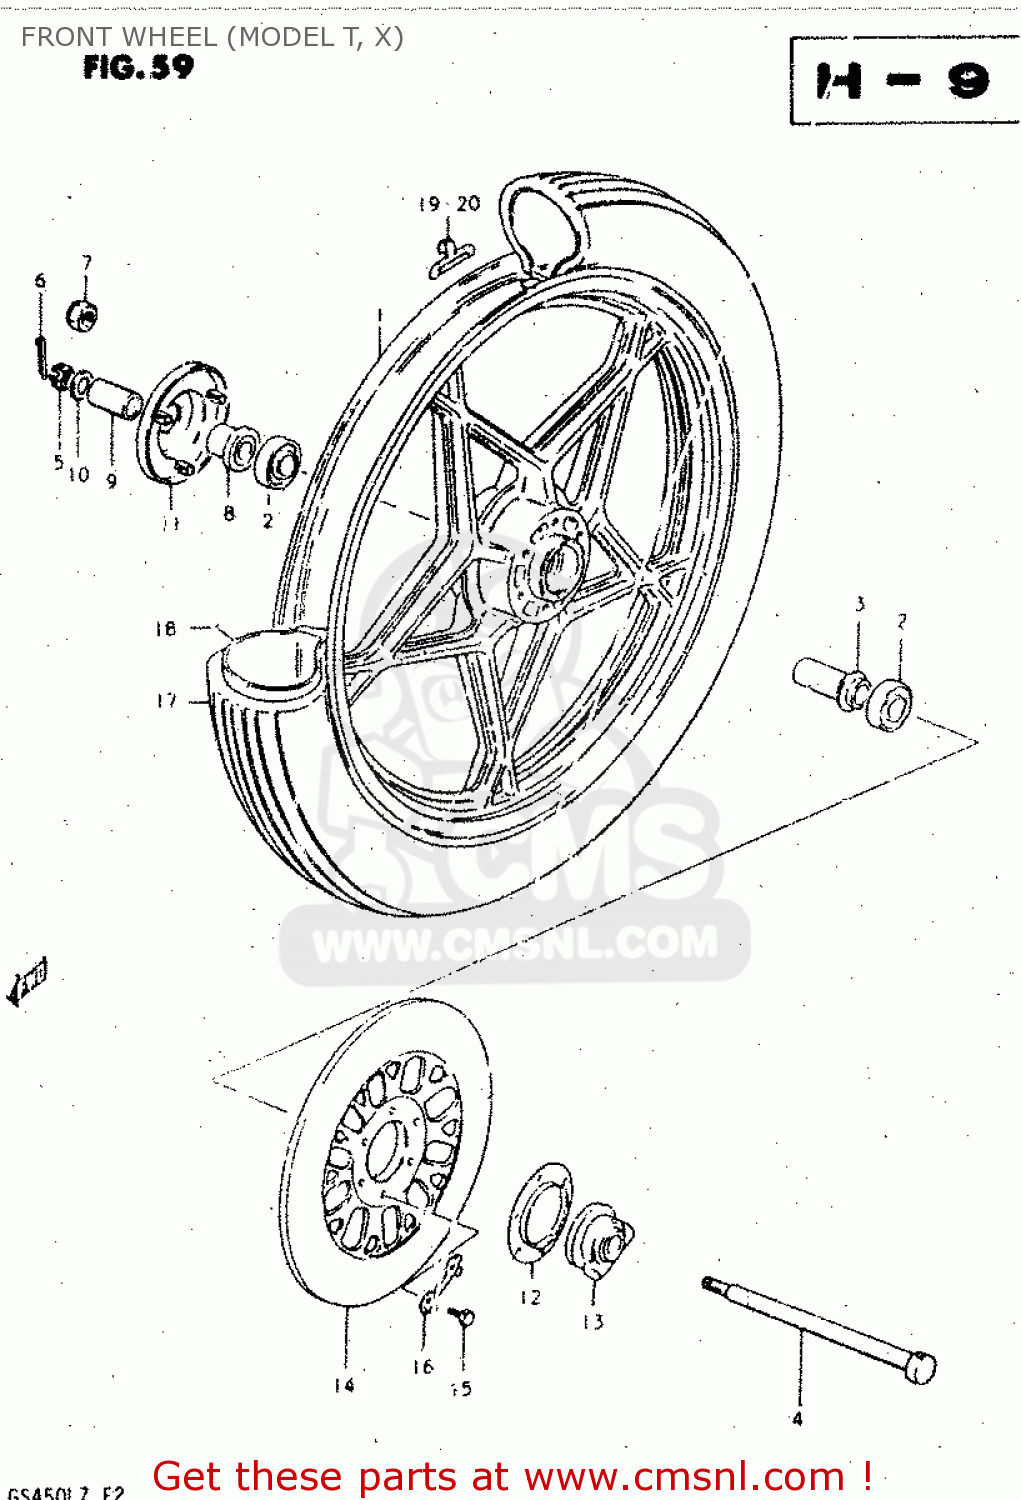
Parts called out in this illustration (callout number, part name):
1	WHEEL (1.9X1.85)
2	BEARING
3	SPACER,FR HUB BEARING
4	AXLE,FRONT
5	NUT 12MM
6	COTTER PIN
7	NUT
8	SPACER,FR HUB BEARING,R
9	SPACER(15X22X30)
10	WASHER
11	COVER,FR HUB,R
12	DUST SEAL,SPEEDOMETER GEAR BOX
13	BOX ASSEMBLY,SPEEDOMETER GEAR
14	DISC,FR BRAKE
15	BOLT(8X25)
16	WASHER
17	TIRE,FRONT
18	TUBE,INNER
19	BALANCER,WHEEL
20	BALANCER,WHEEL
